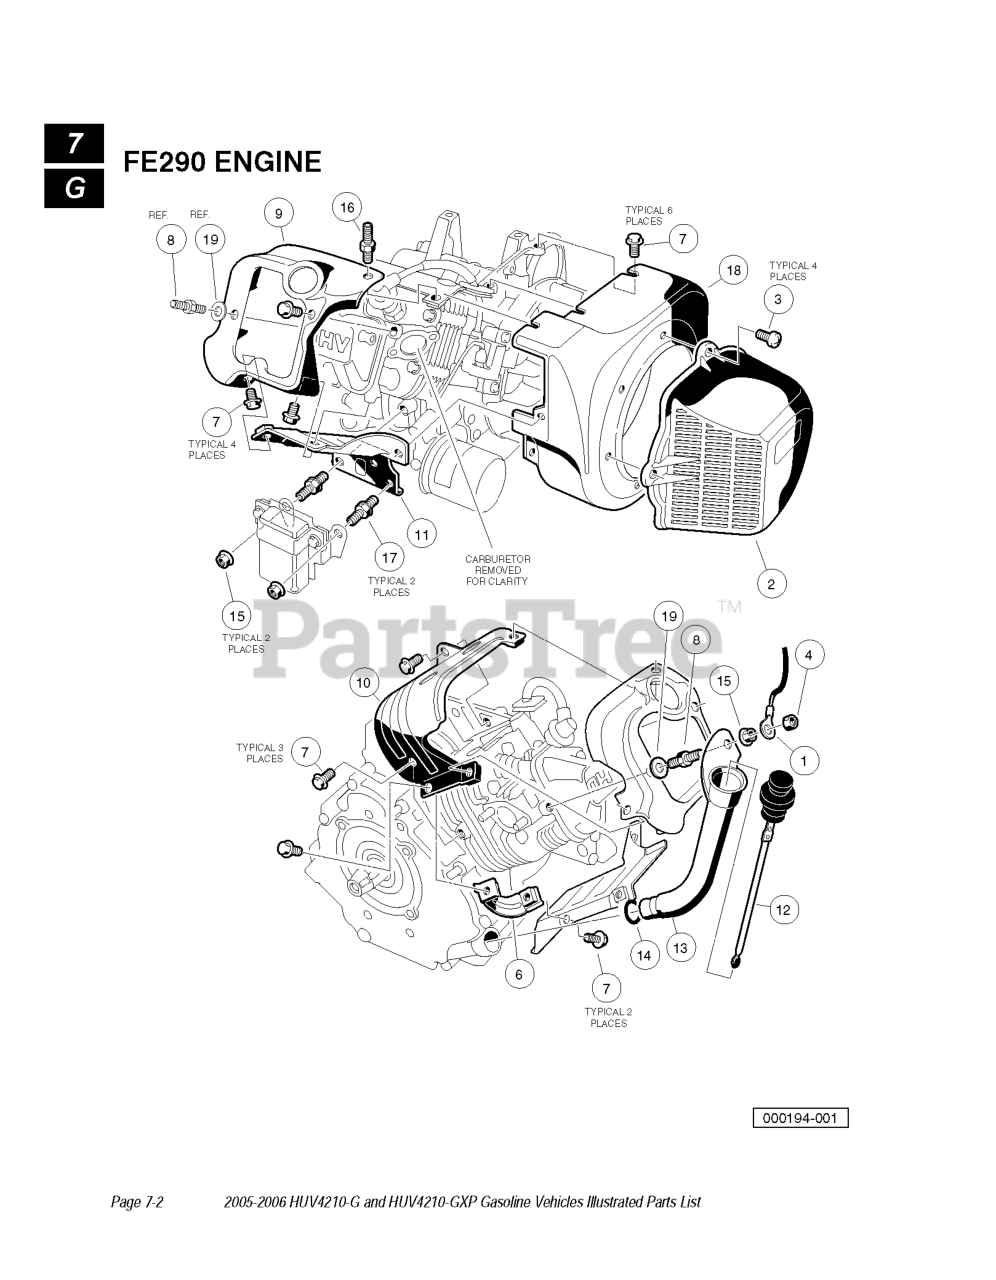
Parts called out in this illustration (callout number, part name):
2	SHROUD, FAN
3	SCREW, M6-1.00 X 10MM PAN HD
4	LOCKNUT, M6-1.00 NYLON INSERT
5	ENGINE, FE290 (CW) 101953901
7	BOLT, FLANGED
9	SHROUD, ENGINE, FE290D
10	SHROUD, ENGINE, FE290D
11	SHROUD, ENGINE, FE290D
13	OIL FILLER TUBE, FE290D
16	SCREW, M6-1.00 STUD
17	STUD, M6-1.00 2-ENDED
18	HOUSING, FE290 FAN
